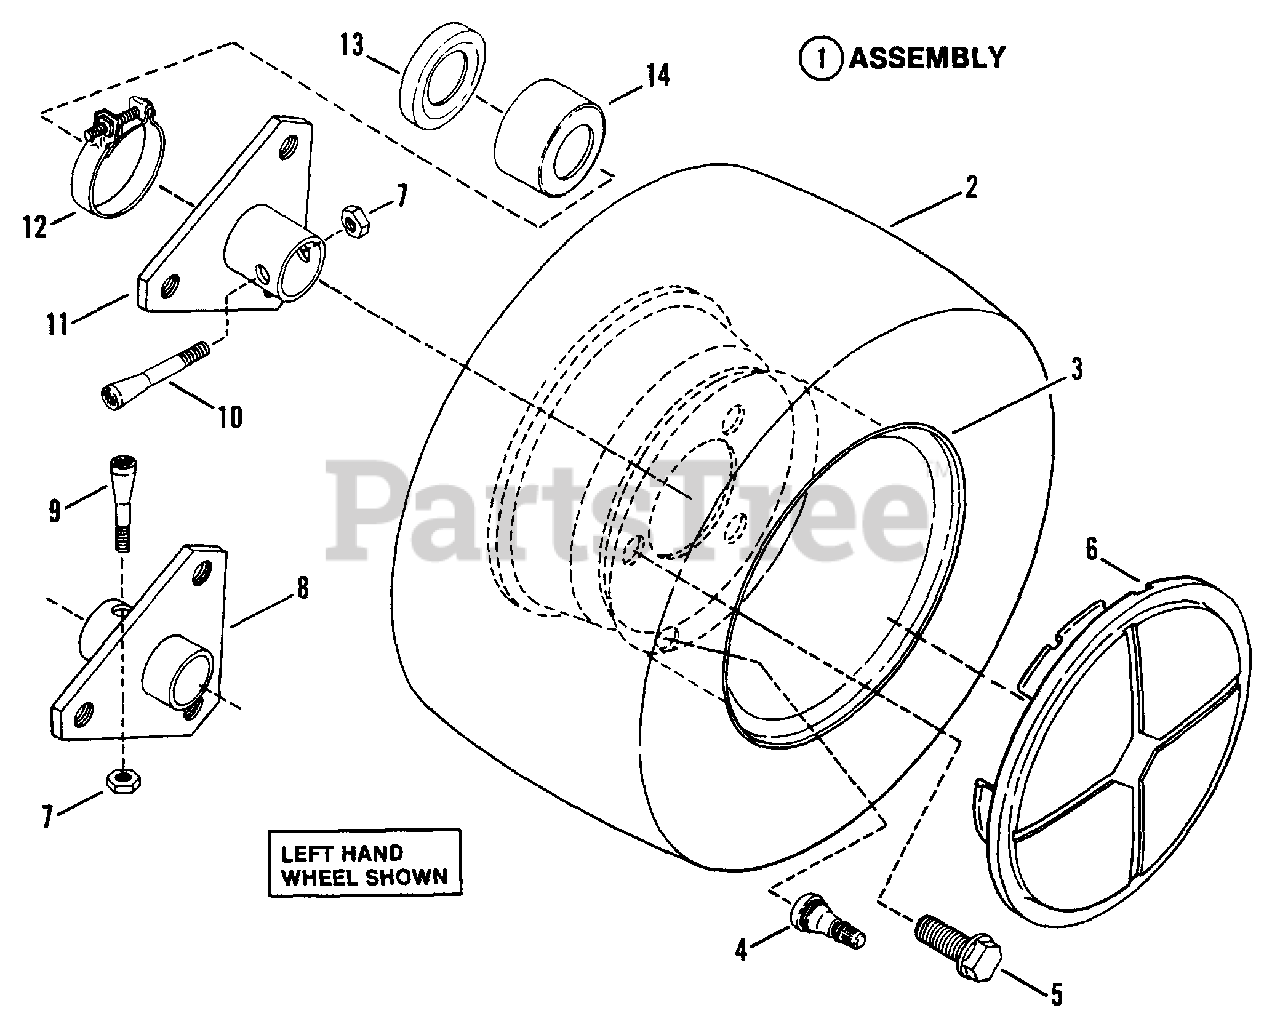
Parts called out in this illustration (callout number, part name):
1	ASSEMBLY, Rear Tire & Rim
2	TIRE, 18-8.50 x 8
3	RIM, 8 x 7
4	VALVE, Air
5	BOLT, 1/2-20 x 3/4" Lug
6	WHEEL COVER
7	NUT, 5/16-24 Hex Lock
8	HUB, Rear Wheel
9	BOLT, 5/16-24 x 2" Tapered
10	BOLT, 5/16-24 x 1 5/8" Tapered
11	HUB, Rear Wheel
12	CLAMP
13	SEAL, Oil
14	CAP, Seal
